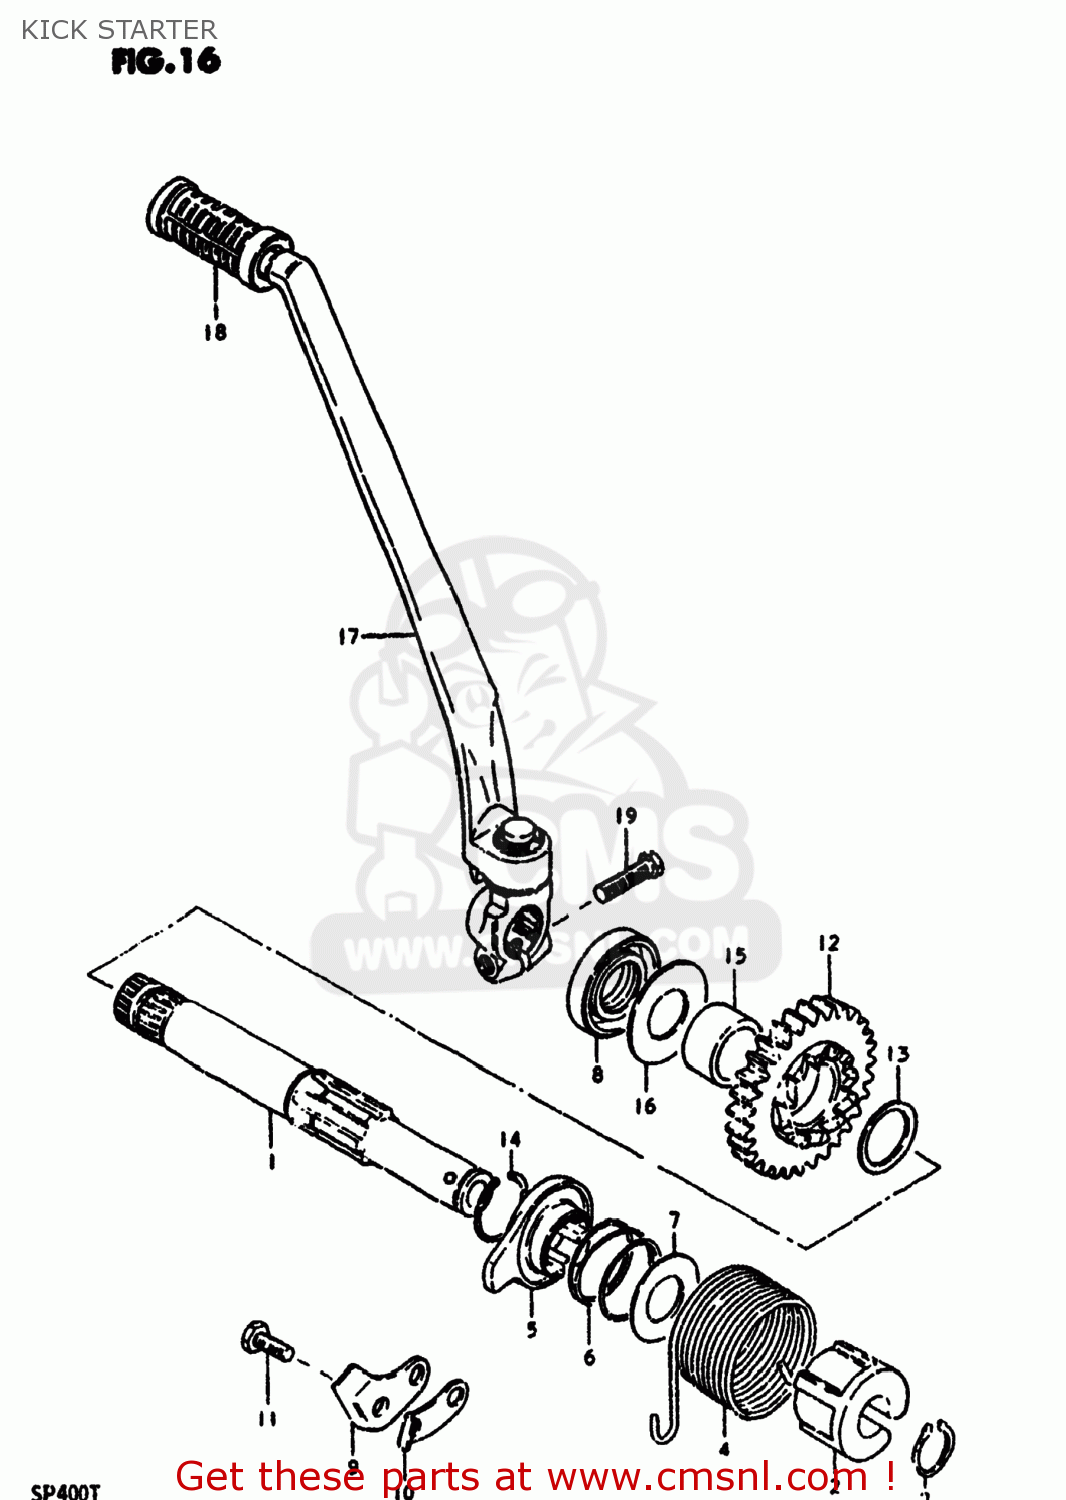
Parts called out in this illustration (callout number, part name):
1	SHAFT,KICK STARTER
2	GUIDE,KICK STARTER SFT SPRING
3	CIRCLIP
4	SPRING
5	STARTER,KICK
6	SPRING
7	PLATE
8	SEAL,OIL(20X37X7)
9	GUIDE,KICK STARTER
10	STOPPER,KICK STARTER
11	BOLT
12	GEAR,KICK STARTER DRIVE(NT:29)
13	WASHER,LOCK
14	CIRCLIP
15	SPACER (20X28X13.8)
16	PLATE, OIL RESERVOR
17	LEVER ASSY,KICK STARTER
18	RUBBER,KICK STARTER PEDAL
19	BOLT(8X25)
